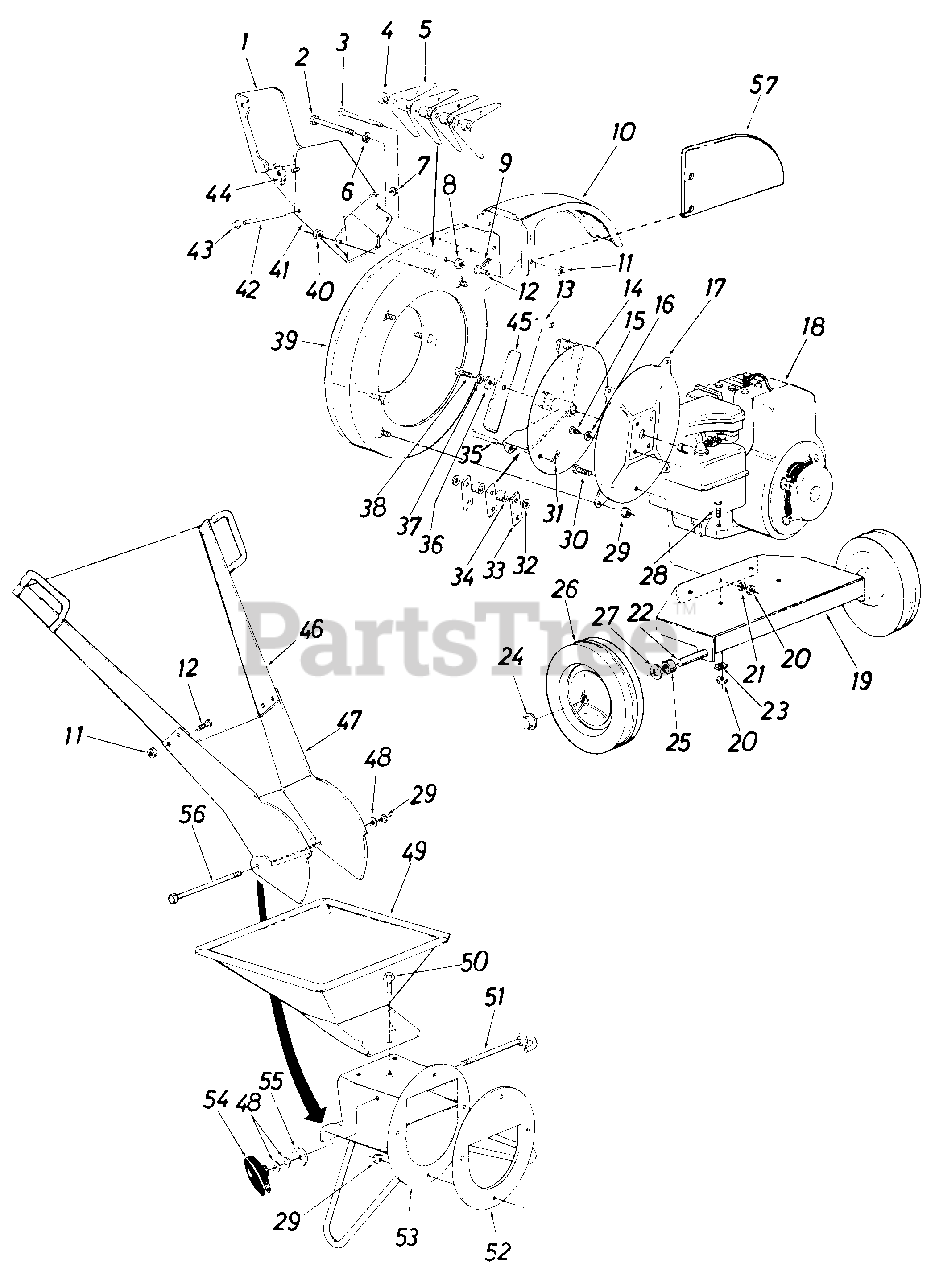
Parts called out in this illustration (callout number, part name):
1	Door Chip It
2	Hex Bolt 1/2-20 x 4.50" Lg.*
3	Clevis Pin
4	Flail Spacer 7/32" Lg.
5	Cutting Finger
6	L.-Wash. 1/2" Scr.*
7	Palnut 3/16" Dia.
8	Hex Jam N ut 1/2-20 Thd.*
9	Cotter Pin 3/32" Dia. x 3/4" Lg.*
10	Chute Deflector
11	L.-Nut 1/4-20 Thd.
12	Hex Bolt 1/4-20 x . 50" Lg.*
13	Sq. Key 1/4" x 2.00" Lg.*
14	Impeller Assembly
15	Hex Bolt 5/16-24 x 3/4" Lg.*
16	L-Wash. 5/16" Scr.*
17	Hopper to Engine Mtg. Plate
18	Engine
19	Engine Mounting Plate
20	Hex Nut 5/16-24 Thd.*
21	L.-Wash. 5/16" Scr.*
22	Shaft
23	Special L.-Wash. 5/16" I.D.
24	Push Cap
25	Spacer
26	Wheel Ass'y.-Comp.
27	Fl.-Wash..50" I.D.*
28	Hex Bolt 5/16-24 x 1.50" Lg.*
29	Elastic Stopnut 5/16-18 Thd.
30	Hex Bolt 5/16-24 x .62" Lg.*
31	Cotter Pin 1/8" Dia. x 1.00" Lg.*
32	Fl-Wash. .531" I.D. x 937 O.D. x .09
33	Flail
34	Flail Spacer 23/32" Lg.
35	Clevis Pin .50" Dia. x 3.0" Lg.
36	Fl.-Wash. .406" I.D. x 1.25" O.D. Hdn.
37	L.-Wash. 3/8" Scr. H.D.
38	Hex Bolt 3/8-24 x 2.00" Lg. H.T.
41	Upper Guide Extension Ass'y.
42	Hinge Pin
43	Palnut 3/16" Dia.
44	Wing Nut E lastic 1/4-20 Thd
46	Guide Extension Assembly
47	Guide Extension
48	Fl.-Wash. 5/16" Scr.*
49	Hopper Assembly
50	Hex Wash. Hd. Self-Tap Scr. 5/16-18 x .50" Lg.
51	Clamp Rod Assembly
52	Back-Up Plate
53	Inlet Guide Assembly
54	Knob Ass'y.
55	Stop Washer
56	Hex Bolt 5/16-18 x 8.38" Lg.
57	Deflector Side Plate
